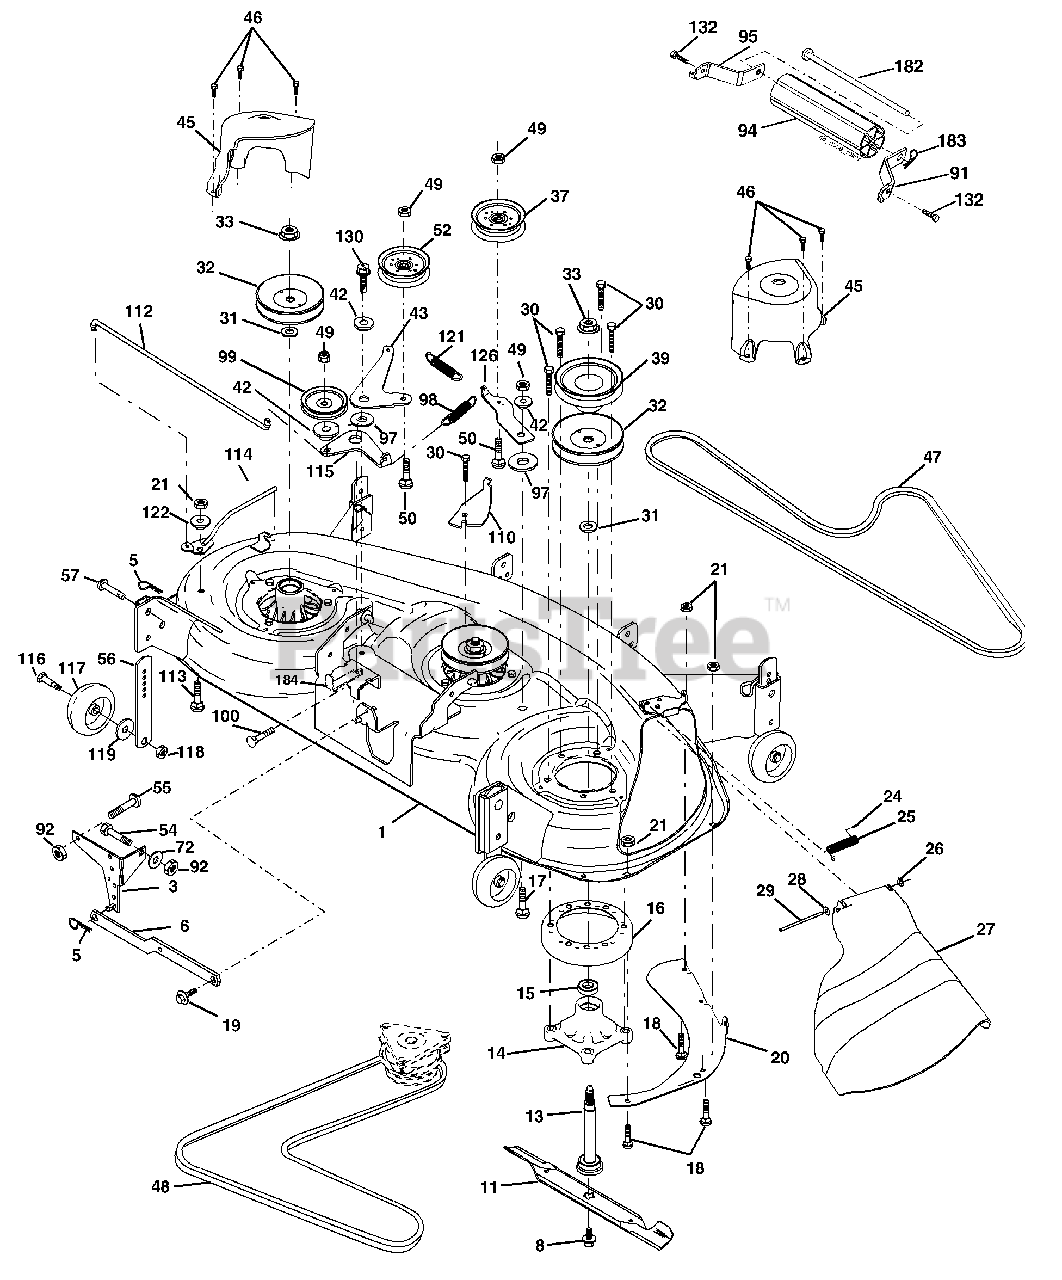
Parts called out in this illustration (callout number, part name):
1	Deck Weldment Mower 48
3	Bracket Asm., Sway Bar
5	Retainer Spring
6	Bar Sway Deck
8	Bolt 7/16 Asm. Blade
11	Blade, 48" Mulching
11	Blade, 48" Hi-Lift
13	Shaft Mandrel Asm. Greaseable
14	Housing Mandrel
15	Bearing, Ball, Mandrel
16	Stripper Mandrel Deck
17	Bolt RDHD Sq Neck 3/8-16 x 1.25
18	Bolt, Carriage 5/16-18 x 5/8
19	Bolt, Hex Hd, Shoulder 5/16-18
20	Baffle, Vortex Mower
21	Nut, Crownlock 5/16-18 unc
24	Cap, Sleeve
25	Spring, Torsion
26	Nut, Push
27	Deflector Shield
28	Washer 11/32 x 5/8 x 16 Ga.
29	Rod, Hinge
30	Screw, Thdroll
31	Washer, Spacer Mower Vented
32	Pulley, Mandrel
33	Nut, Flg. Top Lock Cntr. 9/16
37	Pulley, Idler
39	Pulley, Idler, Driven
42	Spacer, Retainer
43	Arm, Idler Secondary
45	Cover, Mandrel Deck
46	Screw, Thdroll. 1/4-20 x 5/8
47	V-Belt, Mower, Secondary
48	V-Belt, Mower, Primary
49	Nut, Crownlock 3/8-16 unc
50	Bolt, Carr. 3/8-16 x 1-1/2 Gr. 5
52	Pulley Idler Flat
54	Bolt Fin Hex 3/8-16 unc x 1 Gr. 5
55	Bolt Rdhd Sqnk 3/8-16 unc x 1
56	Bar Pnt Adj.
57	Pin Head Rivet
72	Washer 13/32 x 13/16 x 12 Ga.
91	Bracket Asm Noseroller RH
92	Nut Lock Hex w/Ins 3/8-16 unc
94	Noseroller
95	Bracket Asm Noseroller LH
97	Washer Hardened
98	Spring Primary Drive
99	Pulley Idler"V"
100	Bolt RDHD Sqnk 3/8-16 unc x 2
110	Arm Spring Secondary
112	Link Tension Relief Lever
113	Bolt Carr. 5/16-18 x 3/4
114	Tension Asm Relief Lever
115	Arm Spring Tension Relief
116	Bolt, Shoulder
117	Gauge Wheel
118	Nut, Centerlock 3/8-16 unc
119	Washer 3/8 x 7/8 x 14 Ga.
121	Spring Secondary Drive
122	Bushing Pivot Tension Relief
126	Arm, Idler, Primary Deck
130	Screw 3/8-16 x 1
132	Screw 3/8-16 x .75
182	Rod Roller Nose
183	Retainer Spring
184	Keeper Belt Idler
